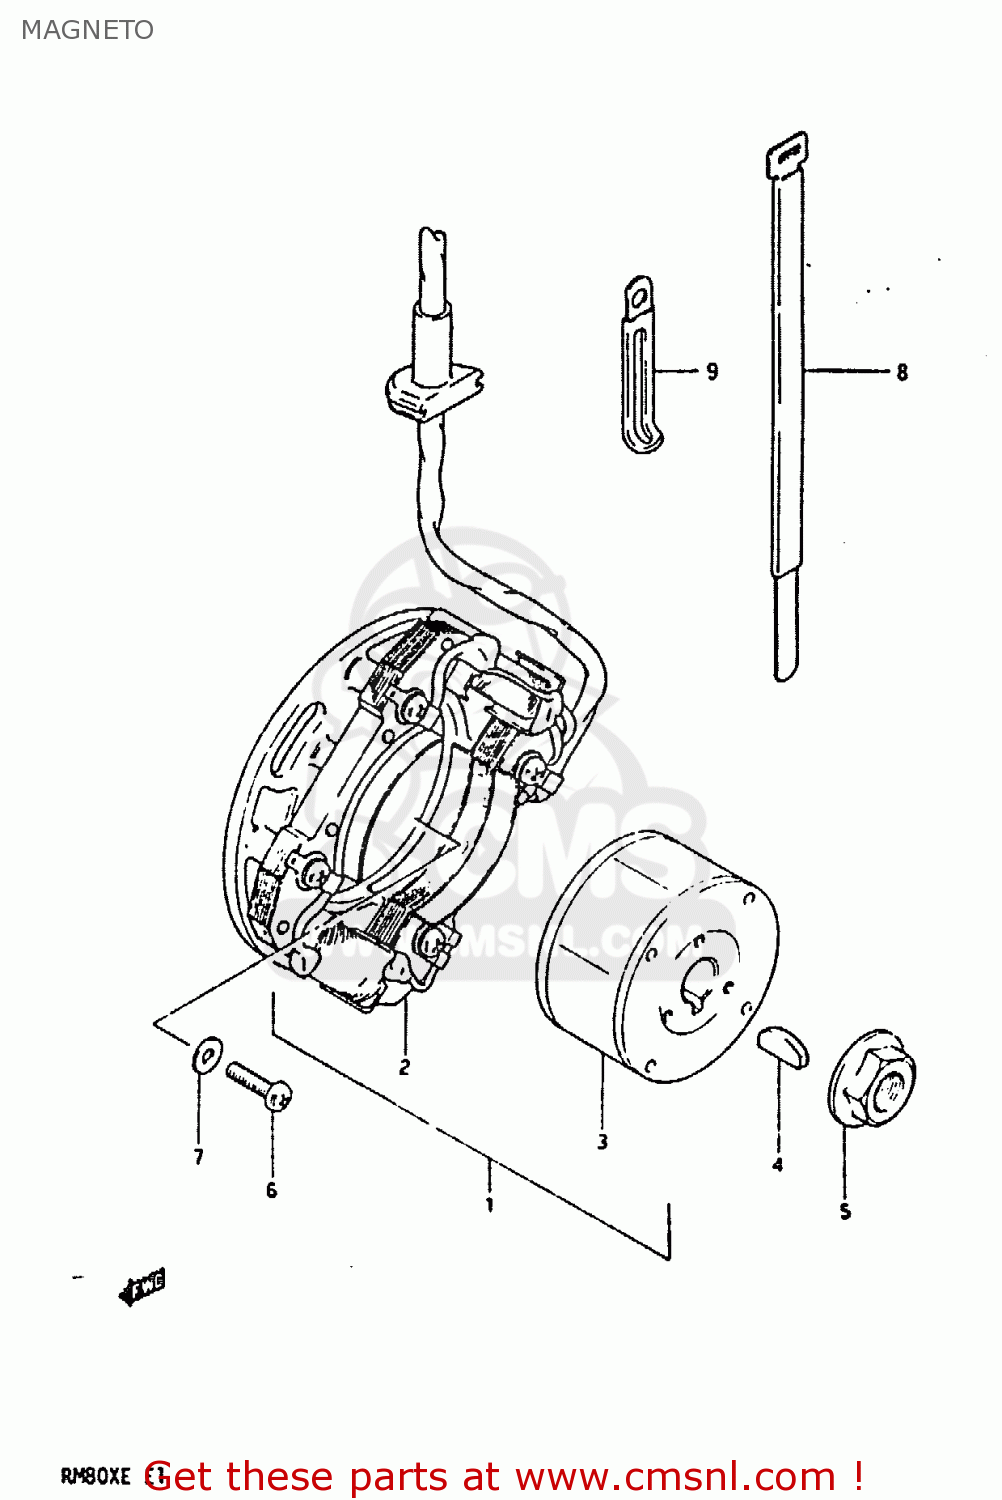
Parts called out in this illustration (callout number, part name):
1	MAGNETO ASSEMBLY
2	STATOR ASSEMBLY
3	ROTOR ASSEMBLY
4	KEY 4MM
5	NUT
6	SCREW
7	WASHER
8	CLAMP(L:250)
9	CLAMP L:35
